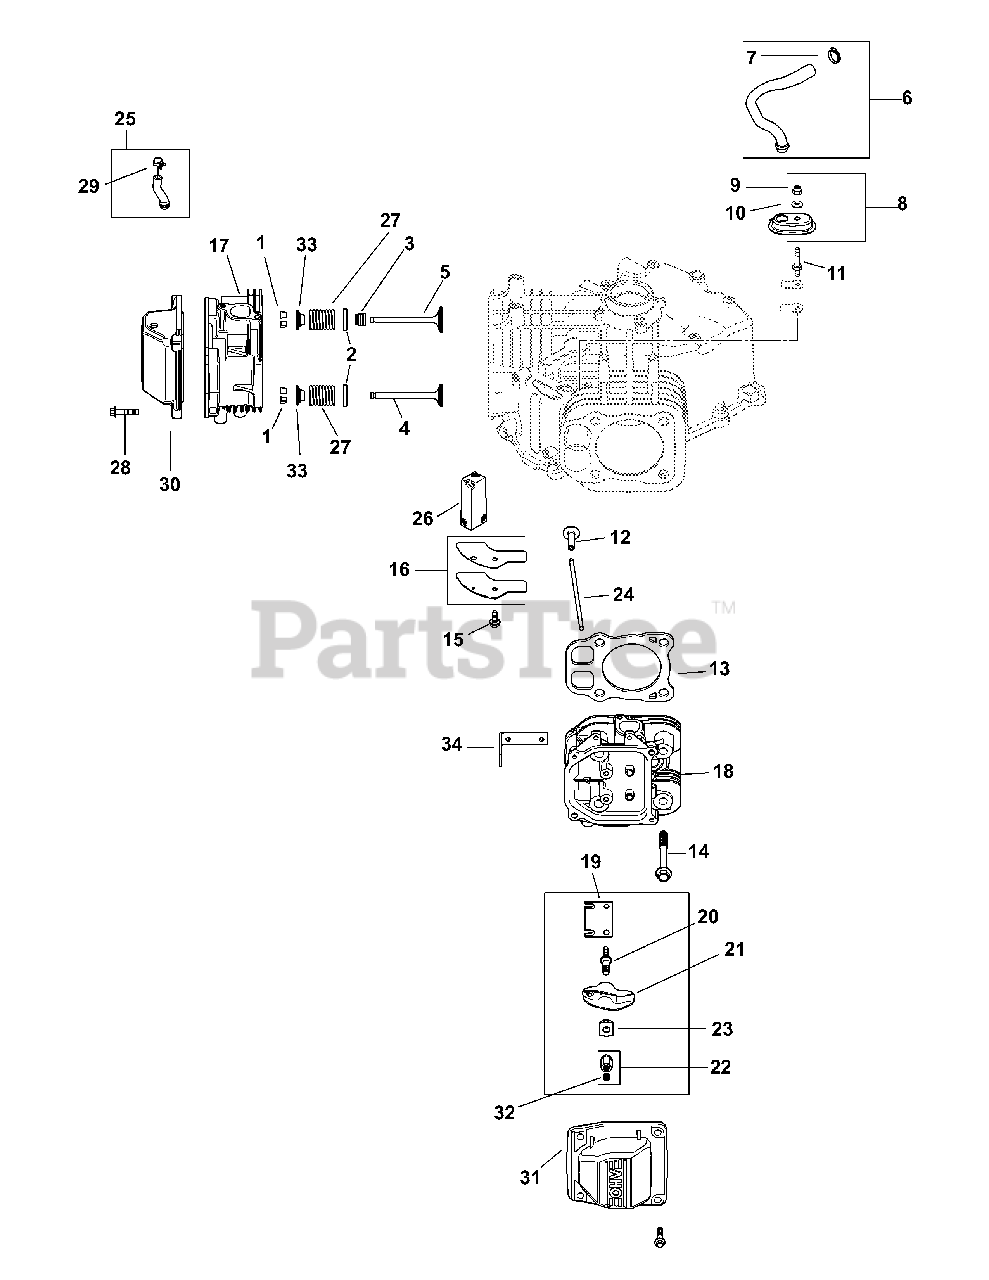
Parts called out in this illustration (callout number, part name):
1	Retainer Kit
2	Spring Retainer
3	Valve Stem Seal
4	Exhaust Valve (STD)
5	Intake Valve (STD)
6	Breather Hose Kit (Inc. #7)
7	Hose Clamp, 1/2
8	Housing Breather Kit (Inc. #9 & 10)
9	Lock Nut, M5 x 8
10	Sealing Washer
11	Breather Cover Stud
13	Cylinder Head Gasket Kit
14	Flange Screw, M10 x 1.5 x 90
15	Flange Screw, M6 x 1.0 x 16
16	Breather Cover
17	Cylinder Head Assembly Kit, #1
18	Cylinder Head Assembly Kit, #2
22	Hex Nut Assembly (Inc. #32)
23	Rocker Arm Pivot
25	Fuel Pump Hose Kit (Inc. #29)
26	Breather Filter
27	Valve Spring
28	Pan Head Screw
30	Rocker Cover
33	Valve Spring Cap
34	Lifting Strap
